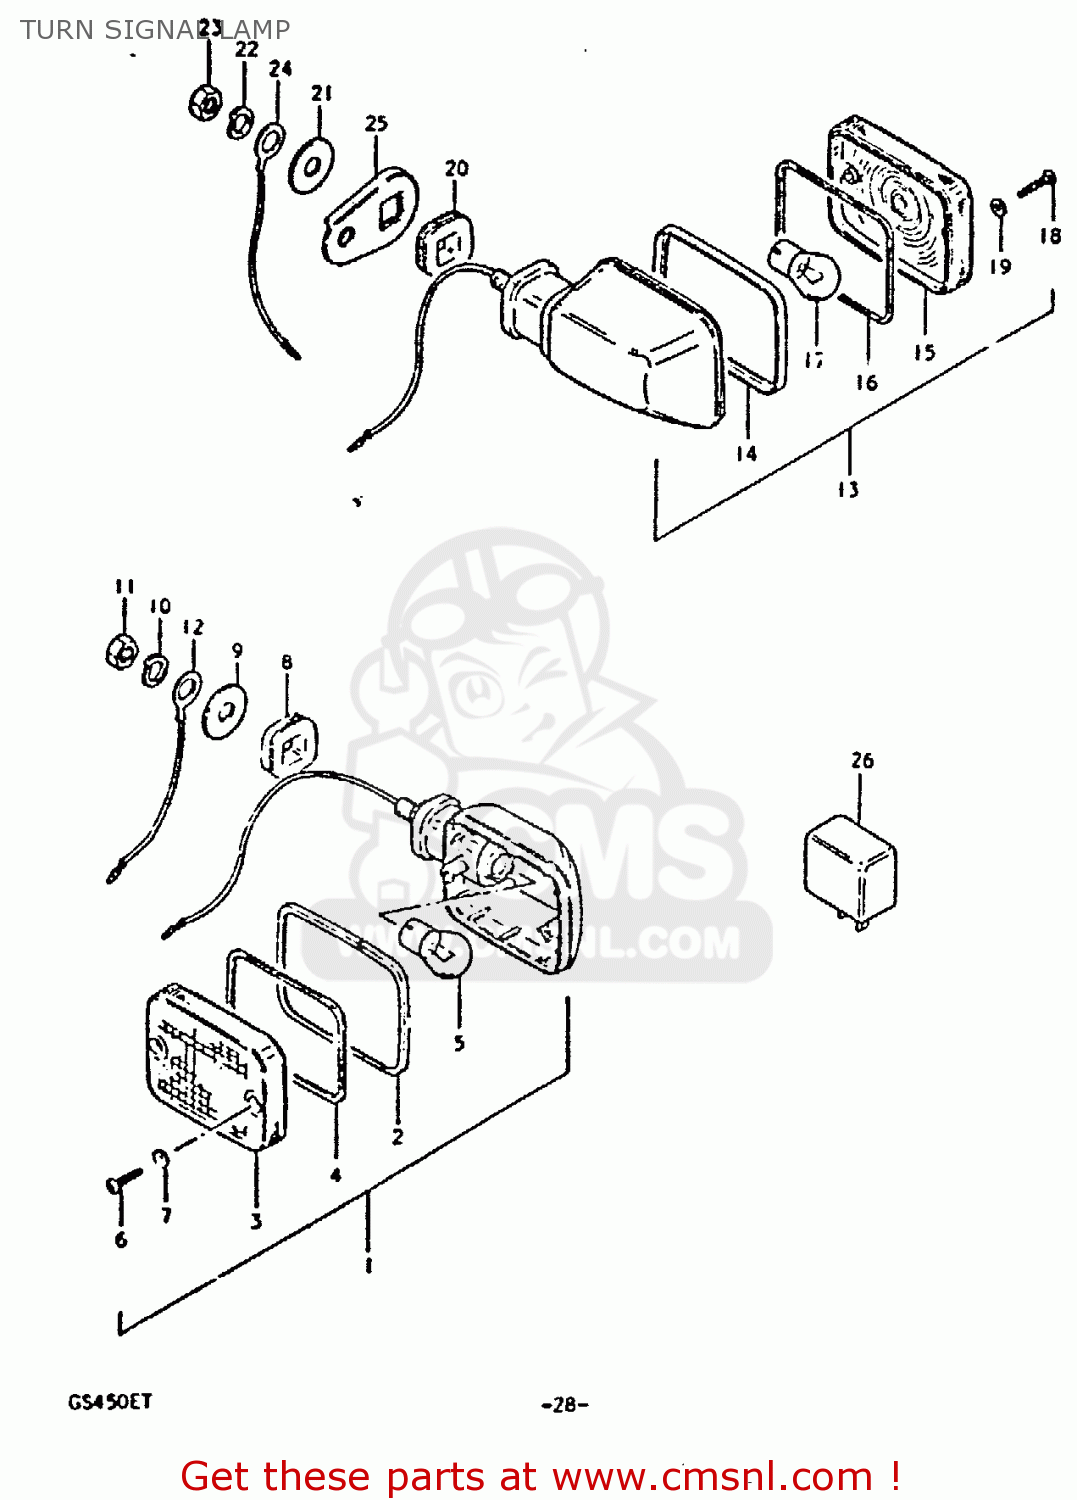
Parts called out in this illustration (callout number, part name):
1	LAMP ASSEMBLY,FRONT TURN SIGNAL
2	RIM
3	LENS
4	GASKET (NAS)
5	BULB(12V23W,STANLEY,A4577A)
6	SCREW
7	GASKET (NAS)
8	CUSHION
9	WASHER (10.5X30X2.3)
10	LOCK WASHER
11	NUT
12	LEAD WIRE,EARTH
13	LAMP ASSEMBLY,FRONT TURN SIGNAL
14	RIM
15	LENS
16	GASKET (NAS)
17	BULB(12V23W,STANLEY,A4577A)
18	SCREW
19	GASKET (NAS)
20	CUSHION
21	WASHER (10.5X30X2.3)
22	LOCK WASHER
23	NUT
24	LEAD WIRE,EARTH
25	BRACKET,RR TURN SIGNAL LAMP
26	RELAY,TURN SIGNAL
